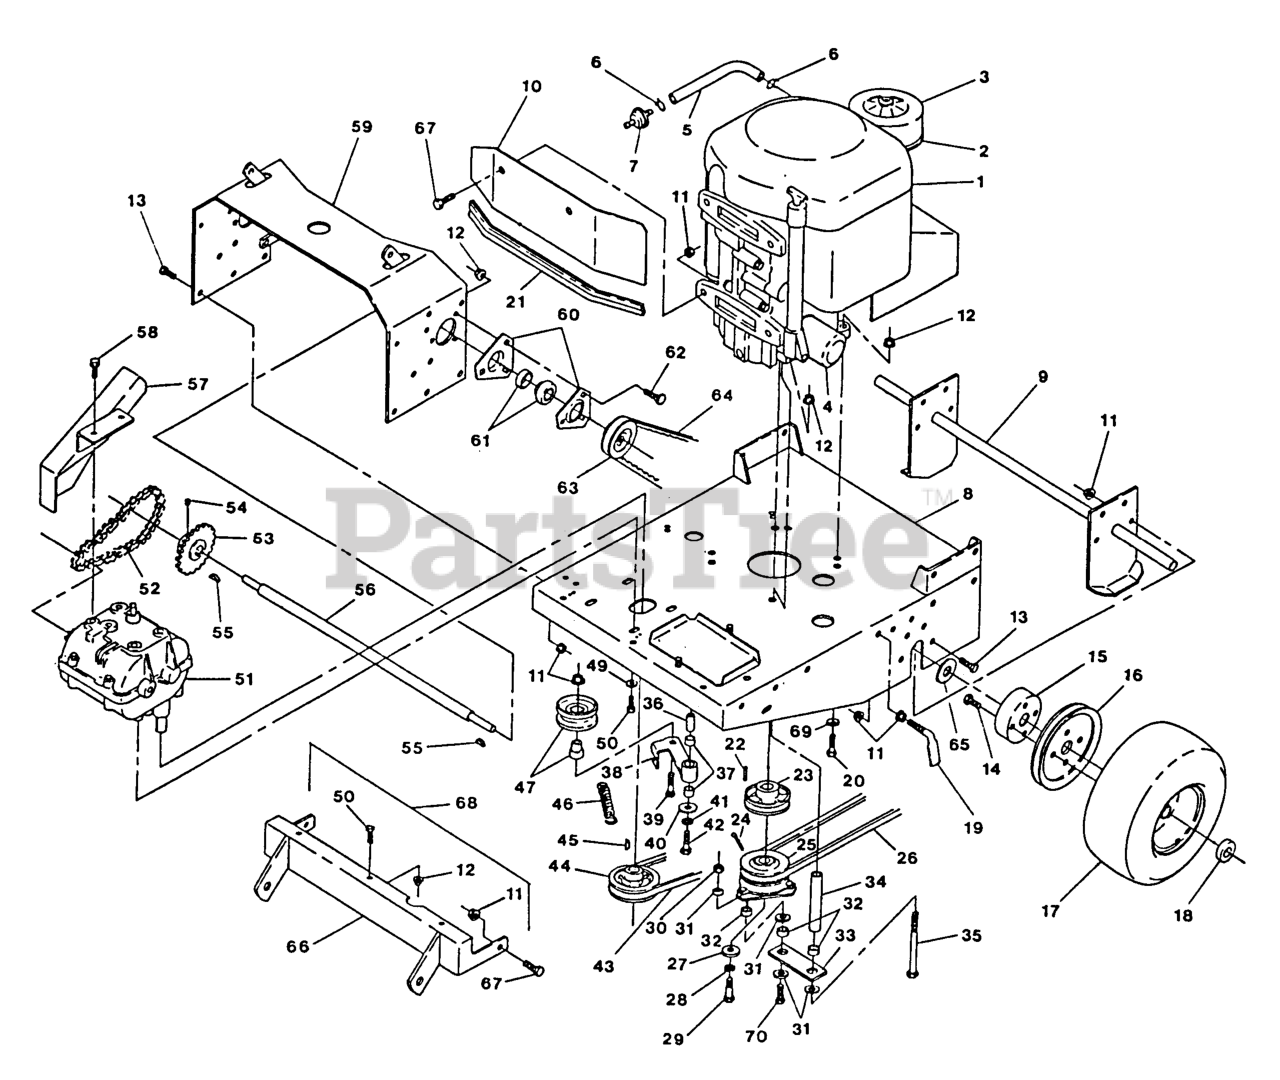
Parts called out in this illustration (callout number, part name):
5	HOSE-FUEL
10	SHIELD-HEAT, TRACER
14	SCRW,TPTTE HH
19	SCRAPER
24	TIE-CABLE
26	BELT,DECK DRIVE
27	BUSHING,CLUTCH KEEPER
28	WASHER-SPRING
36	BUSHING
37	SLEEVE-BEARING
46	SPRING-EXTENSION
47	KIT,48 RH IDLER/BUS
52	CHAIN-#40 ROLLER
54	Set Screw
57	WLD,CHAIN GUARD
60	HOUSING-FLANGE
64	BELT WHL CLTCH W-4.2
66	WLD,SULKY HITCH
68	Turf Tracer Hydro Kit, Hitch Sulky
69	WASHER-SPRING
